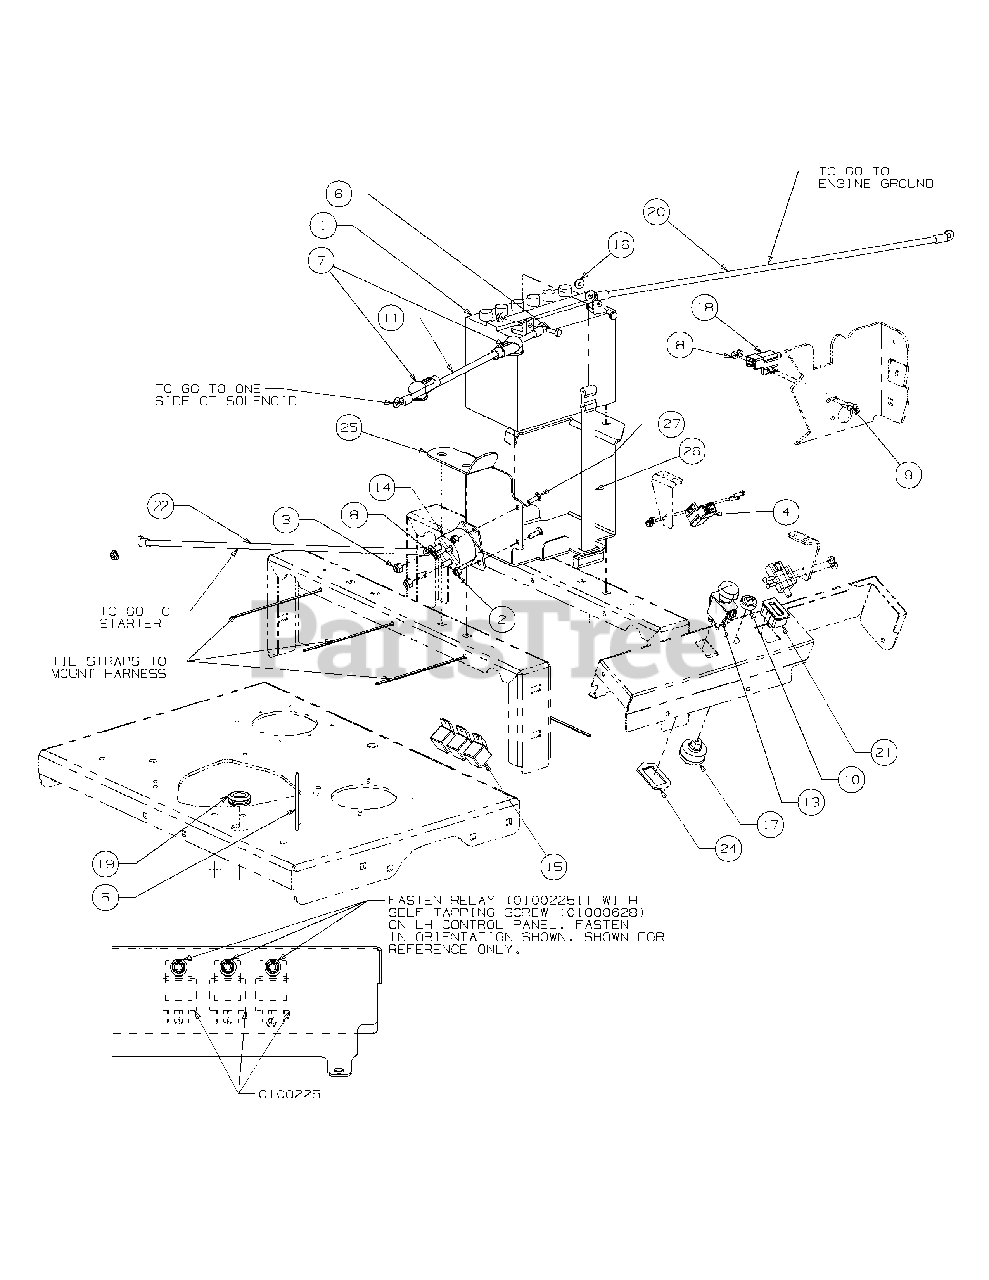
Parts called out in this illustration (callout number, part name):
1	Battery, 12V 225CCA 30 Min
2	Lock Nut w/Nylon Insert
3	Nylock Nut, 5/16-18
4	Switch, Safety
5	Tie, Cable, 3/16 x .05 x 7.4"
6	Screw, Hex, Cap, 1/4-20 x .75
7	Boot, 1" OD Rubber Battery-PST, Red
8	Nut, Lock, Nylon Insert, #10-32
9	Screw, Phillips Head, Machine, 10-32 x 5/8
10	Nut, W/Cap, 5/8-32 Ignition
11	Cable, Battery, Red, 15"
13	Switch, Electric, PTO
14	Solenoid Magnetic Switch
15	Relay, 12V 40A
16	Hex Flange Lock Nut, 1/4-20
17	Switch, Ignition, 6 Pin
18	Switch, Plunger
19	Grommet, .75 ID
20	Cable, Battery Black, 28"
21	Meter, Hour includes:
22	Cable, Battery Red, 32"
24	Bracket, PTO Switch Retainer
25	Mount Bracket, Battery
26	Strap, Battery
27	Carriage Bolt, 1/4-20 x .750
